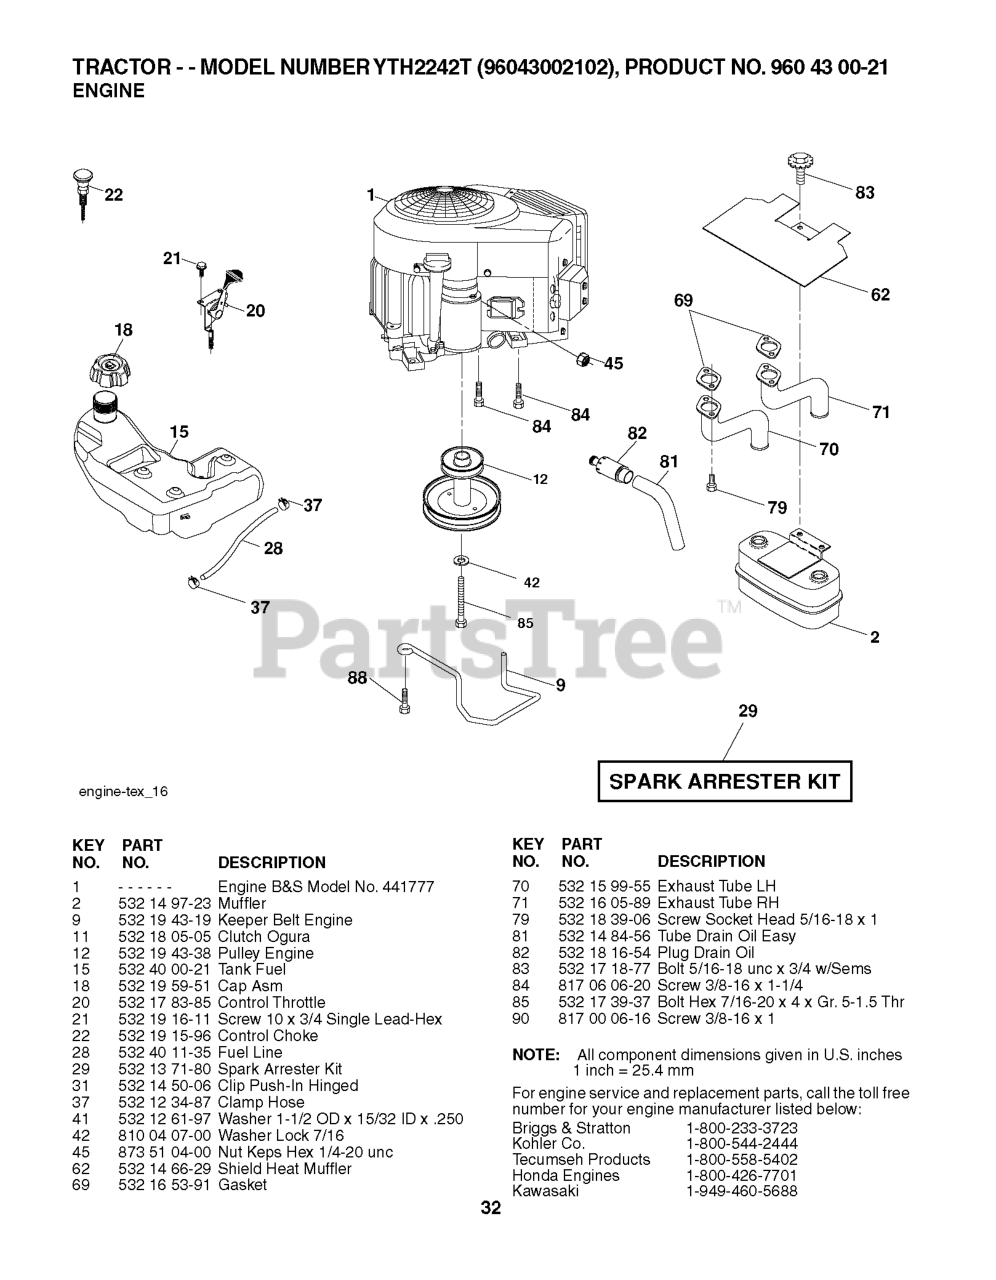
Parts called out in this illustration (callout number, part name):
9	KEEPER.BELT.ENGINE.3.25 (3 2)
11	RB.CLUTCH.OGURA.4.4.PD
12	PULLEY.ASM.ENG.OGURA.3
15	TANK.FUEL.SIDE-FILL.3.NON-EPA
18	CAP.ASM.FUEL.TANK.3"BL
20	THROTTLE CABLE
21	SCREW
22	CONTROL.CHOKE.ERGO.PUSH-IN.BLA
28	LINE.FUEL.64"REAR.EMIS
29	KIT.SPARK ARRESTOR 794945 B&S
37	HOSE CLAMP
42	LOCKWASHER
45	NUT
62	RP SHIELD HEAT MUFFLER
69	GASKET.MUFFLER
70	RP.EXHAUST.TUBE.LH.BS/TWIN
71	EXHAUST.TUBE.RH.BS/TWIN
79	SCREW.SOCKET.HEAD.5/16-18
81	TUBE, DRAIN OIL ASM.
82	PLUG DRAIN OIL EASY
83	BOLT.5/16-18UNCX3/4 W/SEMS.BLK
84	SCREW.3/8-16
85	BOLT HEX 7/16-20X4-1/4"
90	SCREW 3/8-16X1
